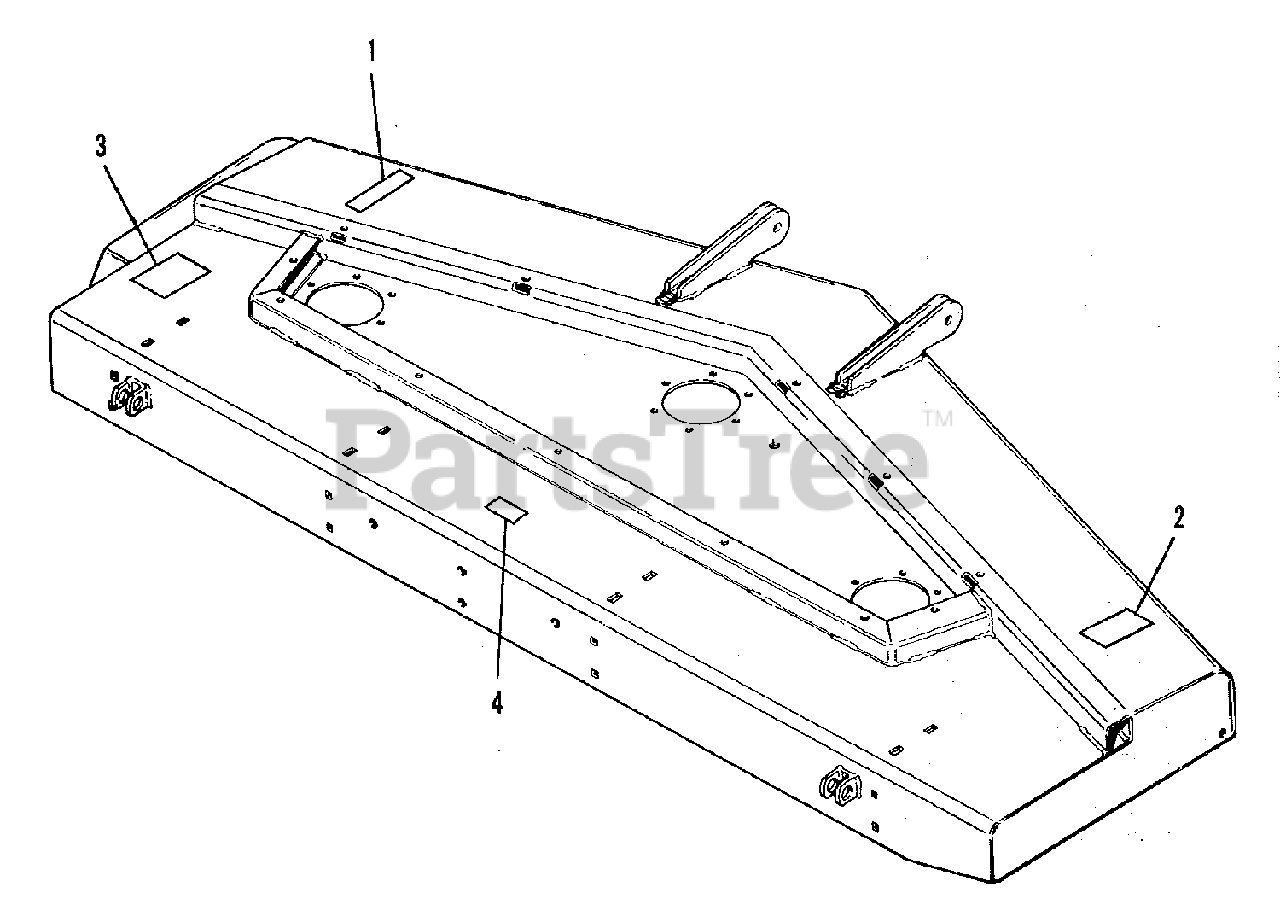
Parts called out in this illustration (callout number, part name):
1	DECAL, Cutting Line
2	DECAL, Danger
3	DECAL, Warning
4	I.D. PLATE (Not Serviced)
